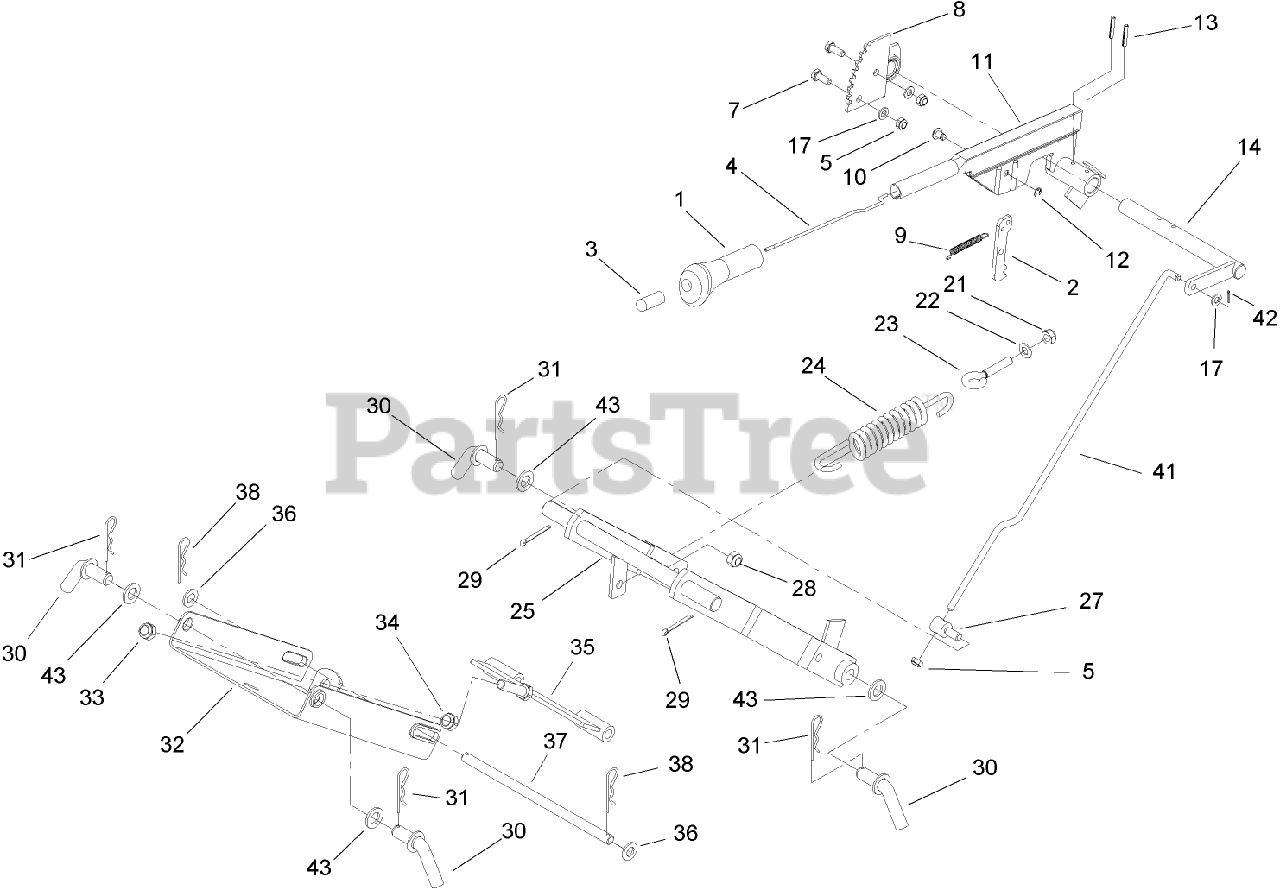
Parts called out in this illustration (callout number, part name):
1	GRIP-HANDLE
2	RATCHET-PLATE, PIVOT
3	BUTTON-PLUNGER
4	ROD-CONNECTION
5	NUT-LOCK, NI
7	SCREW-HH
8	SEGMENT-GEAR
9	SPRING
10	PIN-LEVER, ARM
11	LEVER-ARM, HEIGHT ADJ.
12	CLIP-PIN
13	PIN-SPRING
14	SHAFT-HEIGHT ADJ.
17	WASHER-PLAIN
21	NUT-LOCK, NI
22	WASHER-FLAT
23	BOLT-EYE
24	SPRING-LIFT
25	PIVOT ARM ASM
27	PIN-LIFTING
28	NUT-LOCK, NI
29	PIN-COTTER
30	PIN-BENT
31	PIN-HAIR
32	SUSPENSION-MOWER DECK, FRONT
33	NUT-HEX
34	NUT-HEX
35	HOLDER-FRONT
36	WASHER-FLAT
38	PIN-HAIR
41	ROD-HEIGHT, ADJ.
42	PIN-COTTER
43	Washer-Hose
